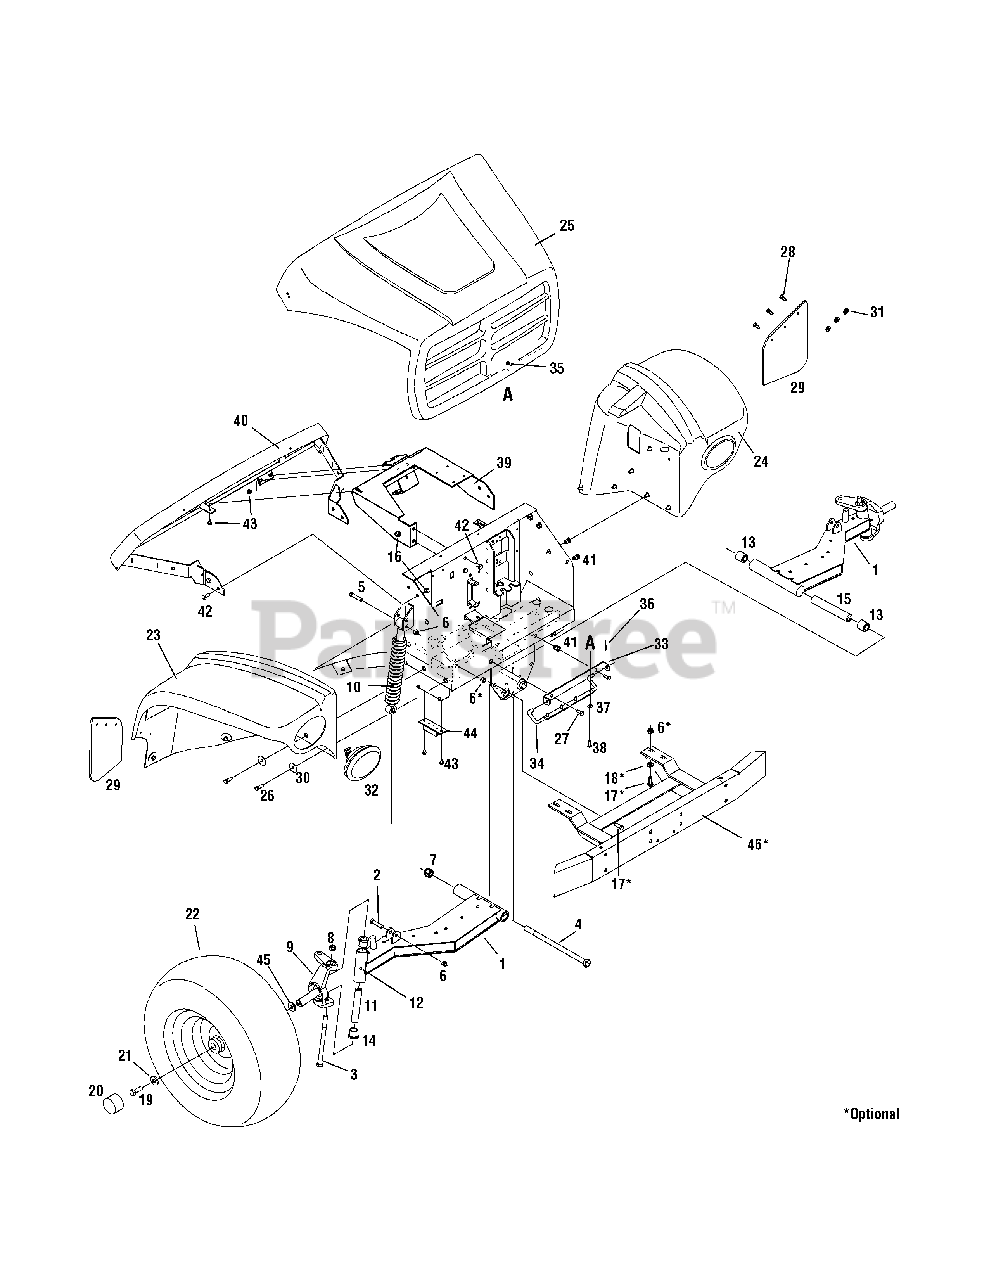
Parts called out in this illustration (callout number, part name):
1	Axle Assembly, Right-front (Incl. Ref 12 - 15)
2	Hex Screw, 3/8-16 x 1.75
3	Hex Screw, 1/2-13 x 7.0, Gr5
4	Hex Screw, 5/8-11 x 11.13, Gr5
5	Hex Screw, 3/8-16 x 2.25
6	Nut, Hex Lock, Nylon, 3/8-16, Gr5
7	Nut, Hex Lock, Nylon, 5/8-11, Gr5
8	Nut, Hex Lock, 1/2-13
9	Steering Control Knuckle, RH
10	Shock Absorber, 2.9 Stroke
11	Tube, .875 x .50 x 4.75
12	Grease Fitting
13	Bearing, .63 ID x 1.19 OD
14	Bushing, Steering
15	Spacer, .645 ID x 1.063 OD
16	Flange Lock Nut, 3/8-16
17	Hex Screw, 3/8-16 x 1.0
18	Flat Washer,.406 x.875 x.059
19	Hex Screw, 1/2-13 x 1.25, Gr5
21	Flat Washer,.531 x 1.25 x.181
22	Wheel Assembly, 23 x 8.5 x 12, RH
23	Panel Assembly, Right Fender, Yellow
24	Panel Assembly, Left Fender, Yellow
25	Panel Assembly, Hood, Yellow
26	Hex Screw 5/16-18 x 1.00 Gr 5
27	Hex Screw, 5/16-18 x.75
28	Pop Rivet
30	Washer, Bell,.39 x 1.38 x.062
31	Flat Washer, .194 x .62 x .063
32	Head lamp Assembly
35	Nut, Hex Lock, 1/4-20
36	Cotter Pin, Internal, 1.42
37	Washer, Flat,.271 x.63 x.065
38	Hex Screw, 1/4-20 x.75
41	Insert Nut, 5/16-18
42	Hex Screw, 3/8-16 x.75
43	Screw, Self-tapping, 1/4-20 x.5
44	Suspension Bumper
45	Flat Washer, 1.030 x 1.625 x.090
